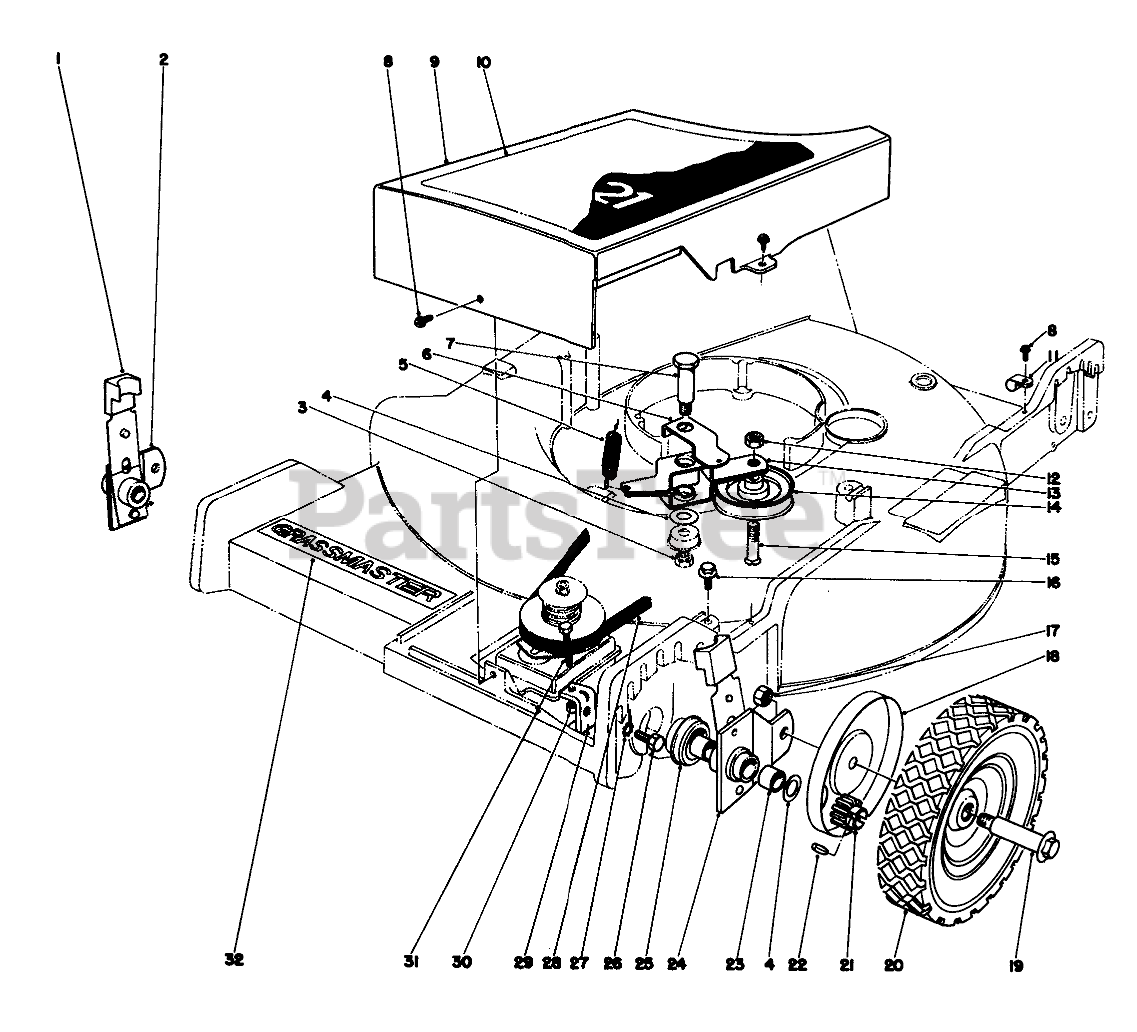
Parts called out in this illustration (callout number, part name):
1	Knob
2	Pivot Arm (Incl. Ref. #23)
3	NUT-HEX
4	WASHER-THRUST
5	TENSION SPRING
6	Idler Bracket Lever
7	SCREW-SHOULDER, HH
8	SCREW
9	Belt Cover
10	Decal Belt Cover
11	CLAMP-NYLON
12	NUT-HEX
13	Idler Bracket
14	V-GROOVE IDLER PULLEY
15	Screw Low Head
16	SCREW-HWHTF
17	Nut
18	WHEEL COVER
20	Wheel & Tire
21	Pinion
22	PIN-GROOVED
23	BUSHING
24	Pivot Arm (Incl. Ref. #23)
25	End Cap
26	SCREW-HH
27	WASHER-LOCK
28	V-BELT
29	Bracket
30	NUT-LOCK
31	Screw
32	Decal Grassmaster
